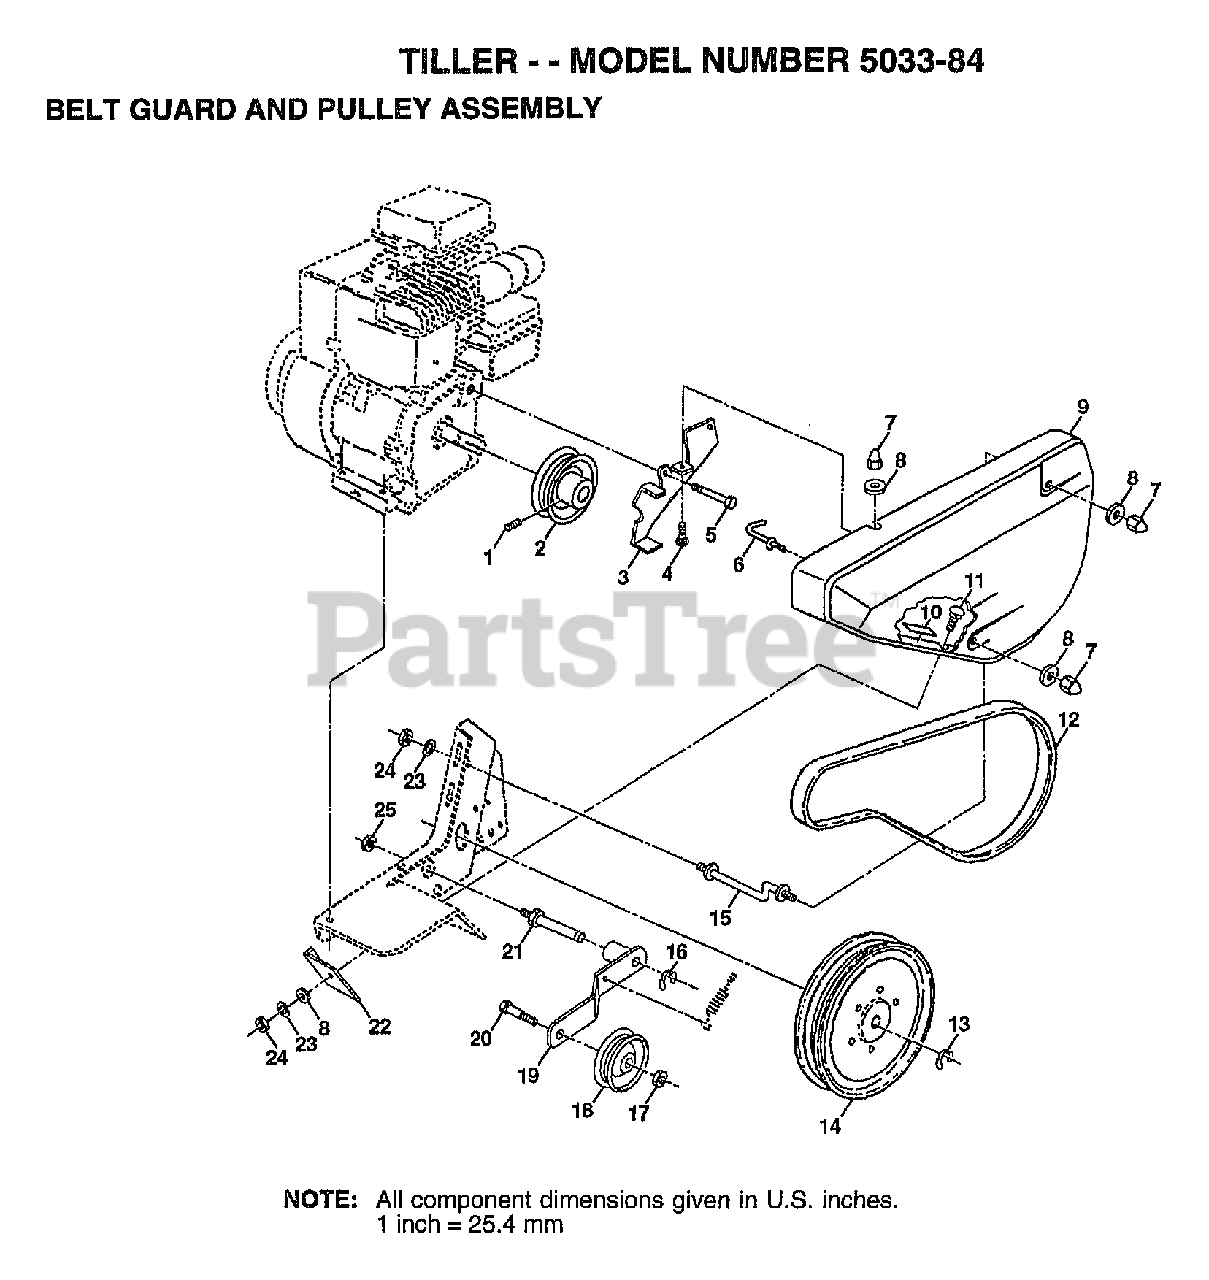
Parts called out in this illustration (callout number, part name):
1	SET SCREW
4	BOLT
5	BOLT.HEX.HEAD
7	NUT-CAP TI
8	WASHER
9	GUARD BELT
10	PAD IDLER TI
11	BOLT T
14	PULLEY.TRANSMISSN
16	KLIP RING TI
17	NUT
18	"PULLEY,IDLER"
19	"ARM, IDLER"
21	SHAFT IDLER TI
22	SHIELD-DIRT TI
23	LOCKWASHER
25	JAM NUT TI
